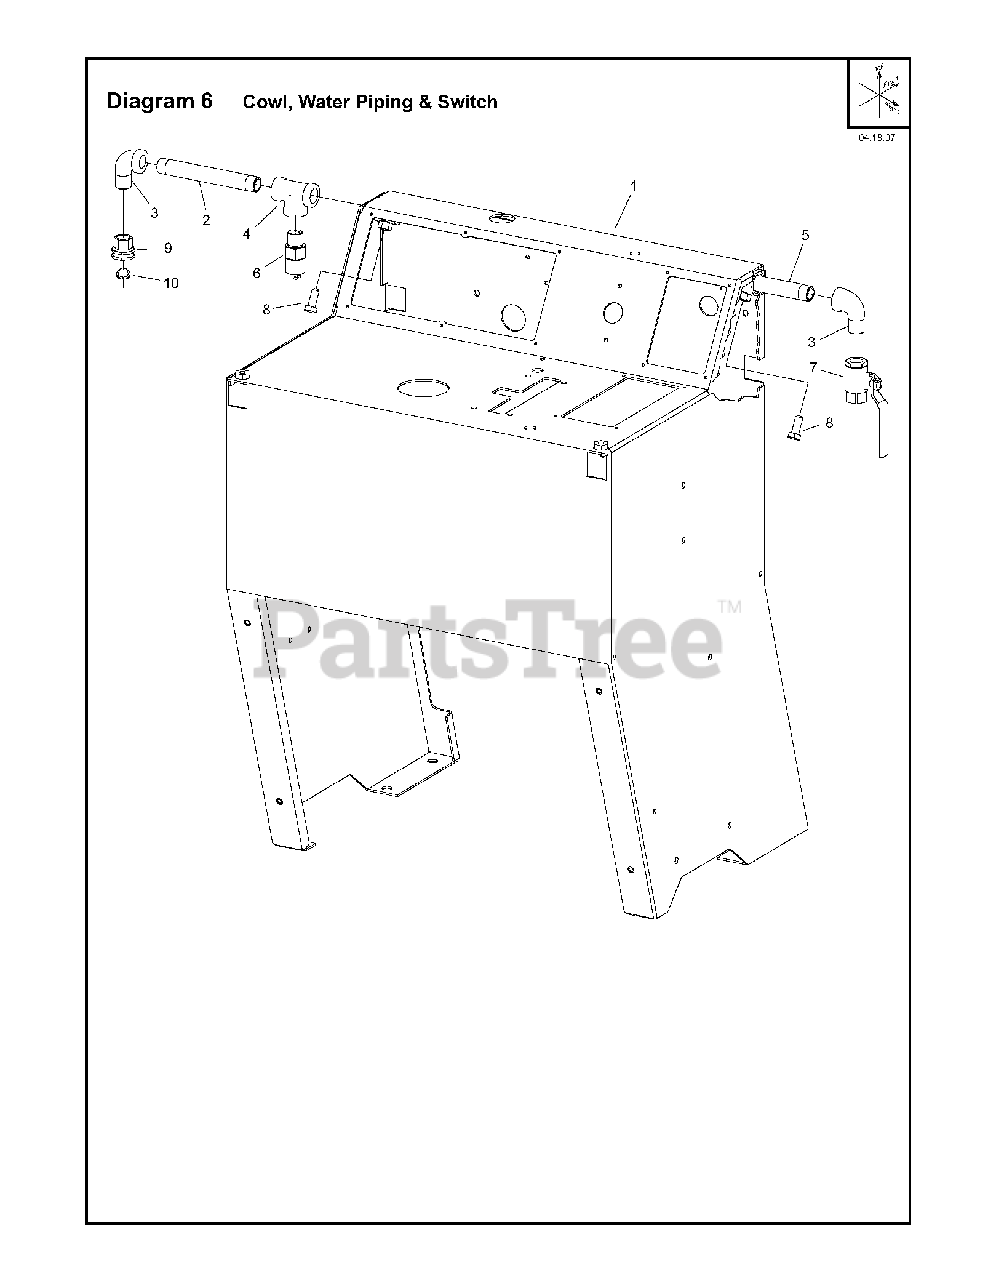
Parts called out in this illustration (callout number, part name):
5	WASHER
6	SWITCH. PRESSURE. N.O.
7	VALVE. BALL WATER SHUT-OFF .5"
8	HHCS. M10 x 1.5 x 25 DIN933 ZP
